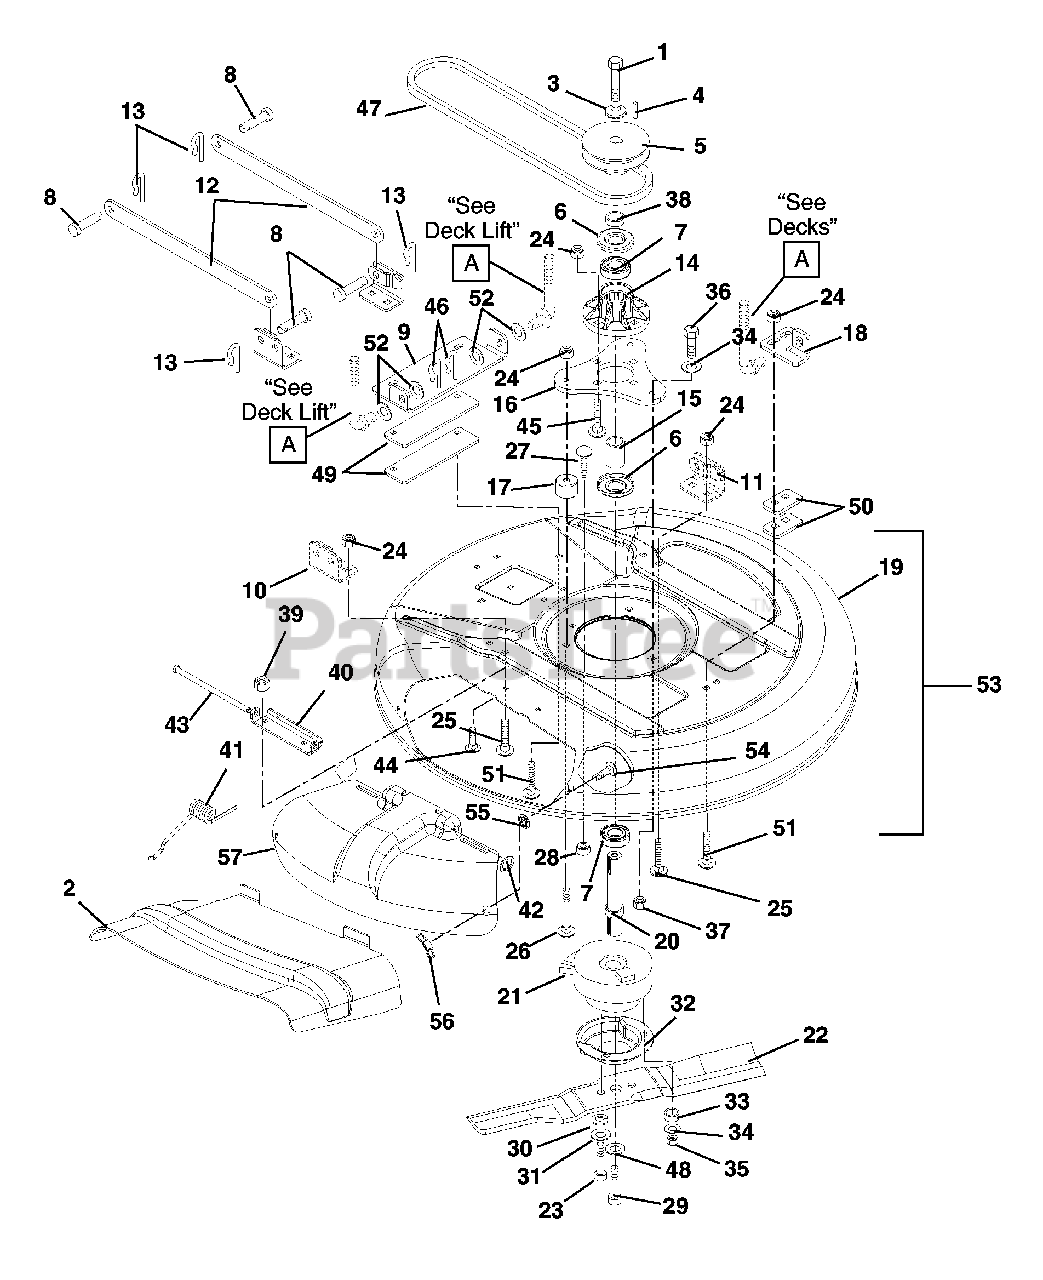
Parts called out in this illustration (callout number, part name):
1	Bolt, Hex .38-16 x 1.00 Grade 8 with Epoxy Patch
2	Chute, Deck
3	Washer, Cupped Serrated .375
4	Key, Square .25 x .38 x .25
5	Pulley, 32" Deck Input
6	Bearing, Slinger
7	Bearing, Ball 1.00 x 2.00 x .56
8	Pin, Clevis .494 x 1.00
9	Bracket, Rear Hanger 32"
10	Bracket, Deck Link Right Hand
11	Weldment, Deck Link Left Hand
12	Link Stabilizer
13	Clip, Spring
14	Assembly, Spindle Housing
15	Spacer, 1.00 x 1.25 x 1.60
16	Spindle, Mount Plate
17	Spacer, Mounting Plate
18	Bracket, Front Lift Hanger
19	Deck 32"
20	Shaft, 32" Input
21	Clutch Kit
22	Blade, 32" Mower
23	Bolt, Hex M10 x 1.25 x 30
24	Nut, Locking Top Flange .38-16
25	Bolt, Round Head Square Neck .38-16 x .75 Grade 5
26	Bolt, Round Head Square Neck .38-16 x 2.25 Grade 5
27	Bolt, Round Head Square Neck .31-18 x 1.50 Grade 5
28	Nut, Spin Lock Flange .312-18
29	Bolt, Button Head .50 x 1.25-20
30	Washer, Locking Metric 10 MM
31	Washer, Flat Steel .406 x 1.00 x .188
32	Shield, Debris
33	Bushing, Bronze .75 I.D. x .88 O.D. x .50 Long
34	Washer, Flat Steel .38 x .875 x .083
35	Nut, Locking Nylon .38-16
36	Bolt, Hex .38-16 x 3.00 Grade 5
37	Nut, Flange .375-16
38	Spacer Steel 1.01 x 1.38 x .509
39	Nut, Locking Center .25-20
40	Hinge Plate
41	Spring, Torsion
42	Ring, Retaining External .312 x .025
44	Bolt, Round Head Square Neck .25-20 x .75 Grade 5
45	Bolt, Round Head Square Neck .38-16 x 1.25 Grade 5
46	Pin, Hair External- #11
47	V-Belt HA, 63.00
48	Washer, Flat Steel .50 x 1.75 x .187
49	Plate, 32" Deck Spacer
50	Plate, 32 Deck Front Hanger
51	Bolt, Round Head Square Neck .38-16 x 1.25
52	Washer, Flat Steel .518 x 2.00 x .105
53	Kit, 32" Deck Assembly Service
54	Bolt, Round Head Square Neck .31-18 x .75 Grade 2
55	Nut, Push .312
56	Nut, Nylock Wing .312-18
57	Cover, Mulch 32" Deck
